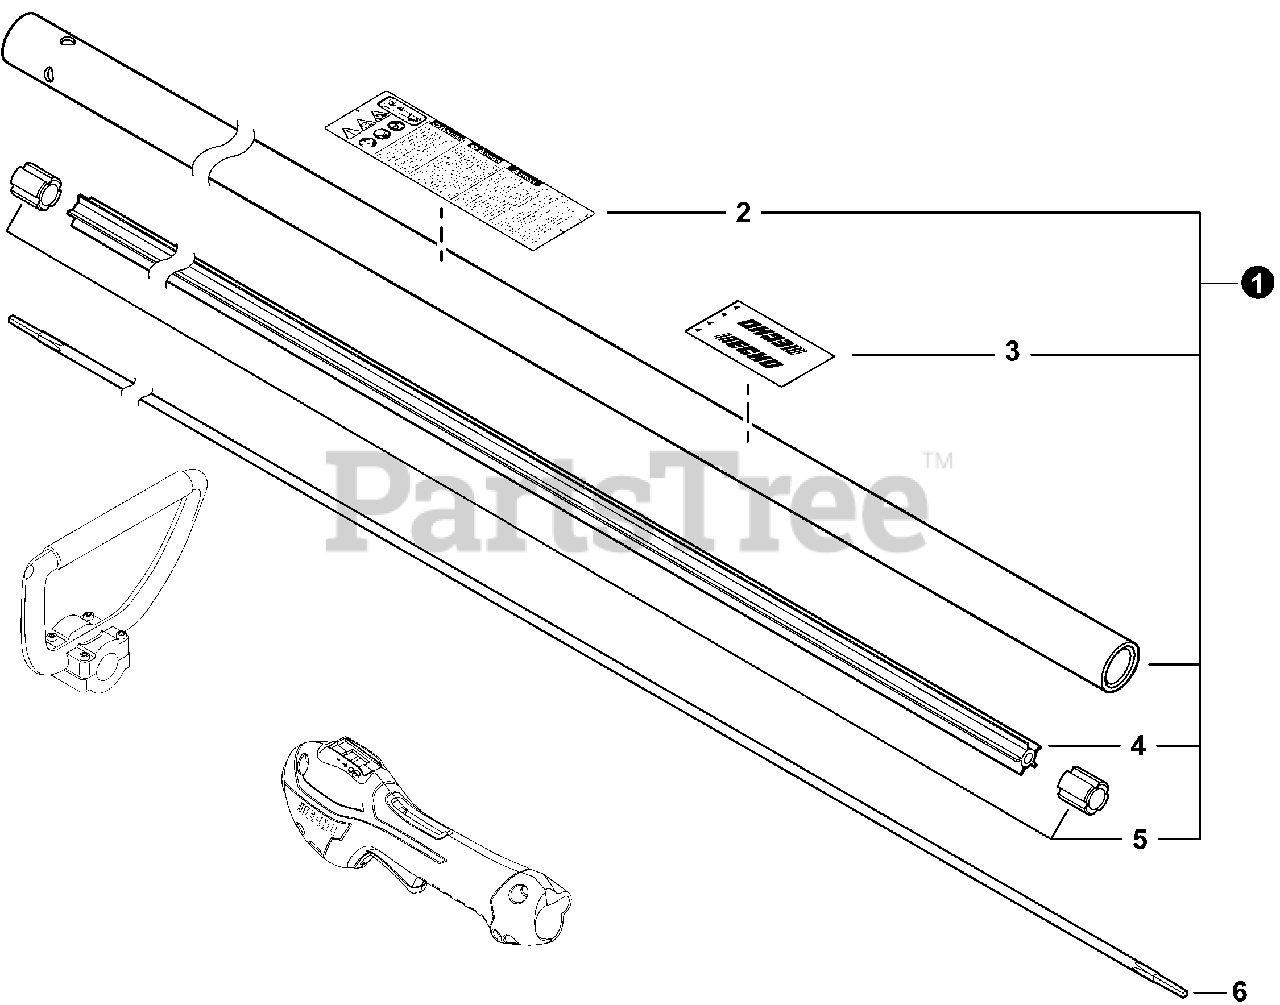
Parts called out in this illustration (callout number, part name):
1	MAIN PIPE ASSY
2	LABEL, CAUTION
3	LABEL, HANDLE LOCATION
4	LINER, FLEXIBLE 21.6×1420
6	DRIVESHAFT - FLEXIBLE
